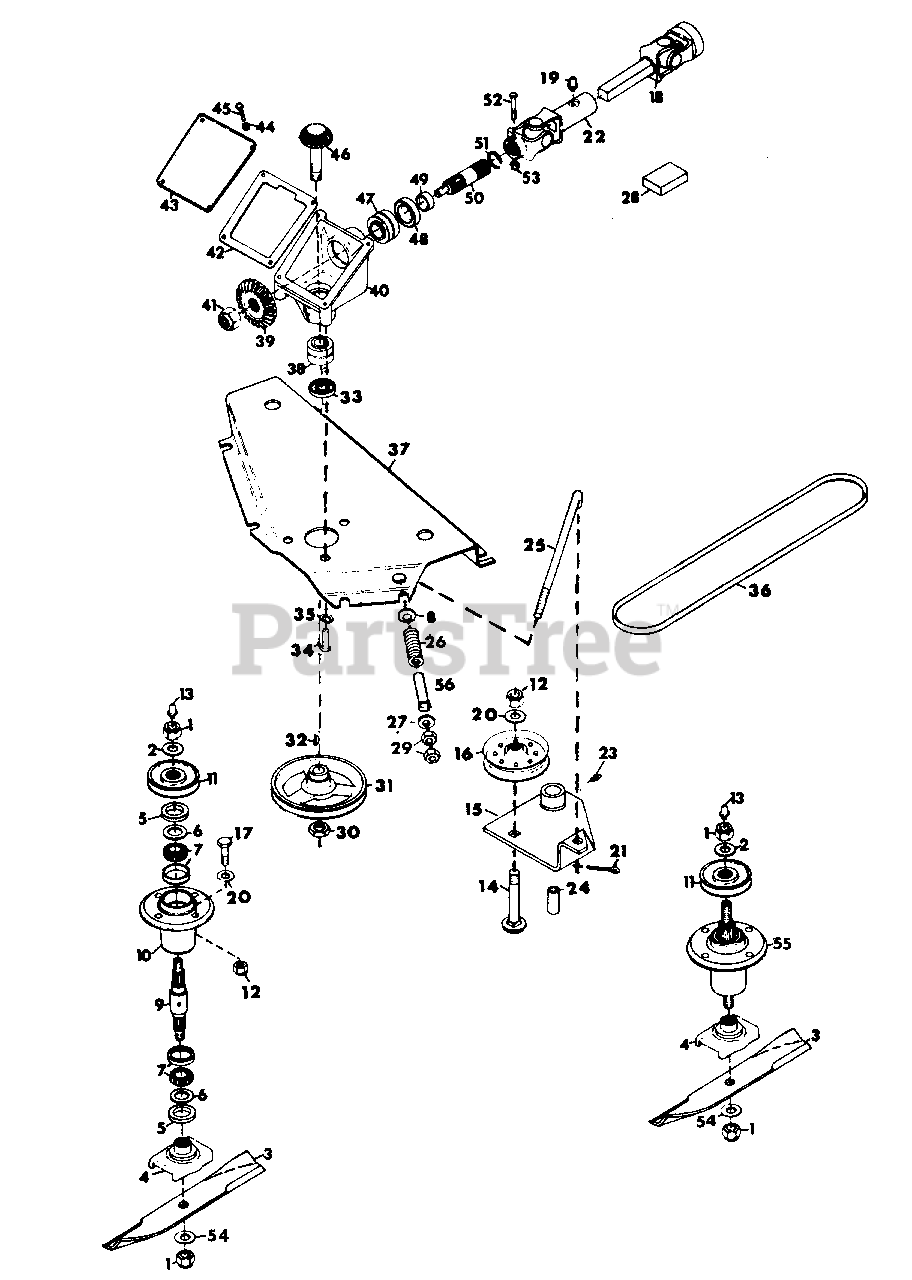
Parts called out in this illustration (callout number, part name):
1	NUT, LOCK; 5/8-11 WASHER INSERT HEX
2	WASHER, FLAT; .656X1.312X.095
3	BLADE
4	CRADLE, BLADE
5	SEAL, STEEL
6	WASHER, FLAT; .975X1.970X.030
7	ASSEMBLY, BEARING
8	WASHER, CUP
9	SHAFT, SPINDLE
10	HOUSING, BEARING
11	SHEAVE, SPINDLE
12	NUT, LOCK; 3/8-16 WASHER INSERT HEX
13	FITTING, LUBE; 1/8
14	BOLT; 3/8-16X2 RD HD SQ NK
15	WELDMENT, IDLER PIVOT
16	SHEAVE, IDLER
17	BOLT, HEX; 3/8-16X1.25
18	U-JOINT, MALE END
19	FITTING, LUBE; 1/4-28
20	WASHER, FLAT; .433X1.000X.038
21	PIN, COTTER; .062X1.000
22	U-JOINT, FEMALE END
23	FITTING, LUBE; 1/4-28
24	SPACER
25	ROD, IDLER
26	SPRING
27	WASHER, FLAT; .406X.812X.065
28	KIT, REPAIR; UNIVERSAL JOINT(NEAPCO)
29	NUT, HEX; 3/8-16
30	NUT, JAM; 3/4-10 HEX HEAVY
31	SHEAVE, DRIVE
32	KEY, WOODRUFF; .188X.625 HARD
33	SEAL, OIL; 1.250X1.686X.313
34	BOLT, HEX; 1/2-13X1
35	WASHER, LOCK; 1/2 REG
36	V-BELT
37	GUARD, BELT
38	ASSEMBLY, BEARING
39	GEAR, BEVEL
40	CASTING, GEAR BOX
41	NUT, LOCK; 3/4-10 WASHER INSERT HEX
42	GASKET, GEAR HOUSING
43	COVER, GEAR HOUSING
44	WASHER, LOCK; 1/4 REG
45	BOLT, HEX; 1/4-20X.50
46	SHAFT, GEAR PINION
47	ASSEMBLY, BEARING
48	SEAL, OIL; 1.250X1.987X.250
49	SPACER
50	SHAFT
51	RING, RETAINING; 1.000 SHAFT
52	BOLT, HEX; 1/4-20X2
53	NUT, LOCK; 1/4-20 WASHER INSERT HEX
54	WASHER, FLAT; .687X1.312X.130
55	ASSEMBLY, SPINDLE
56	SLEEVE, ROD
